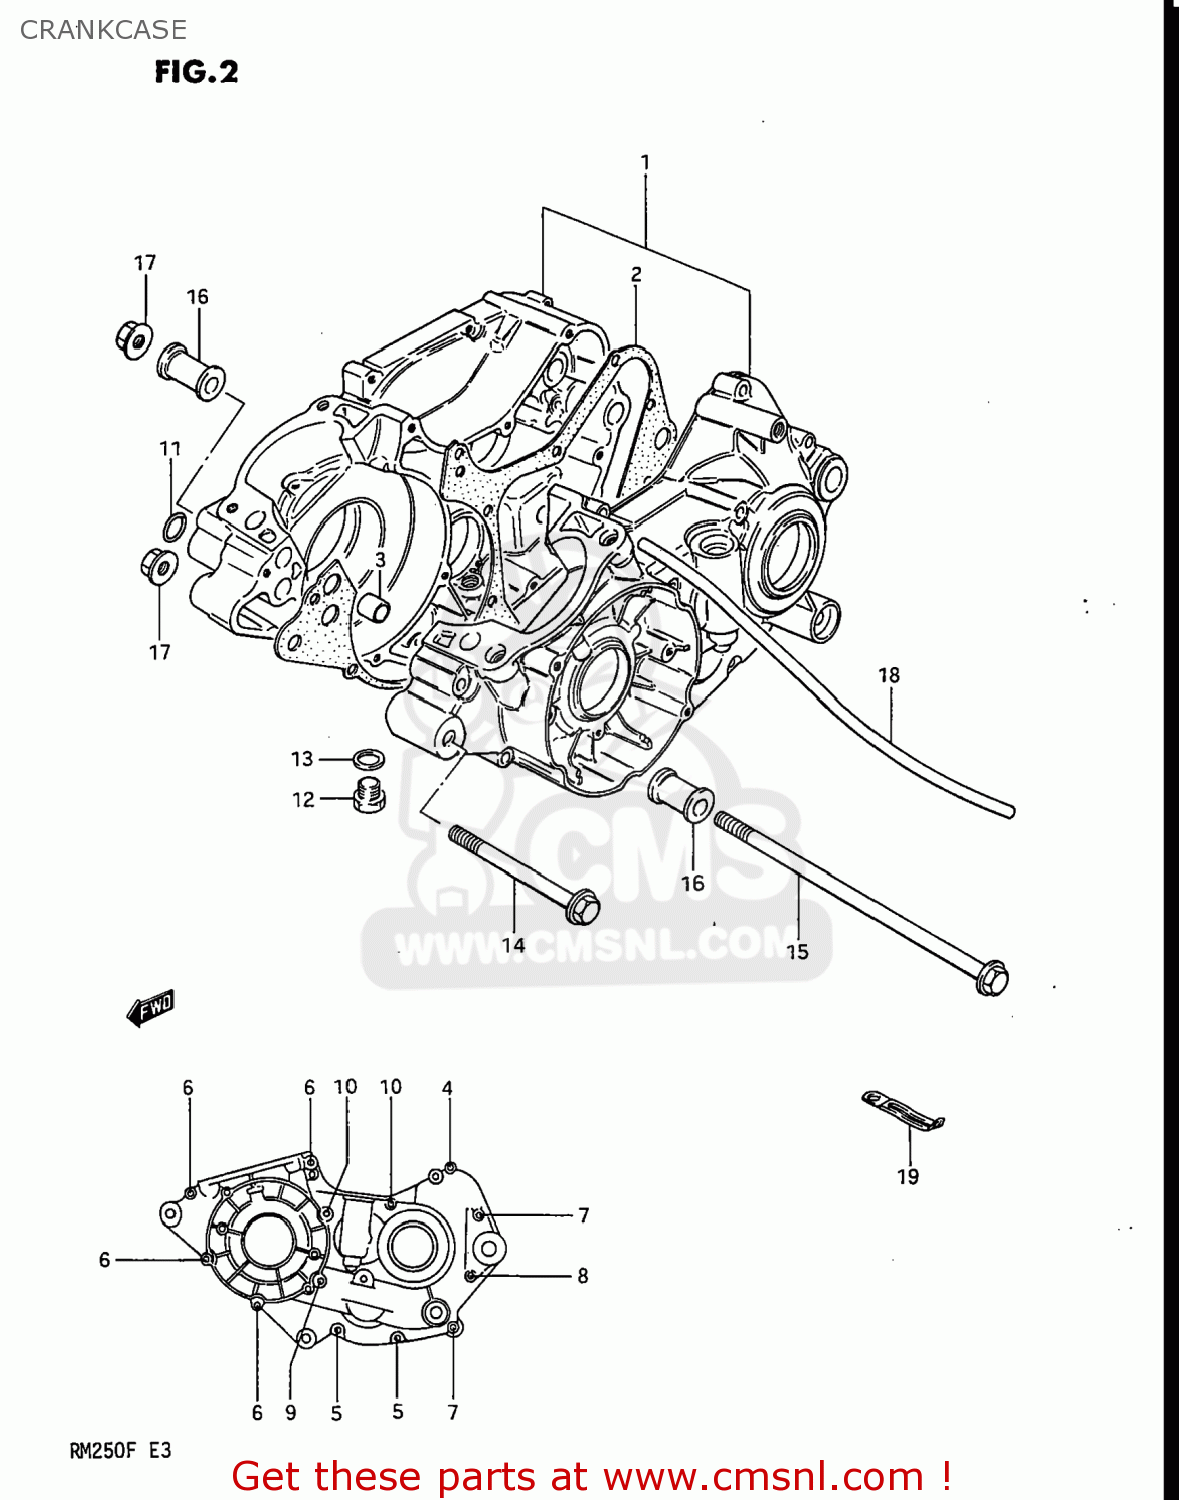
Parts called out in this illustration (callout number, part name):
1	CRANKCASE SET
2	GASKET,CRANKCASE (MCA)
3	PIN
4	SCREW
5	SCREW
6	SCREW
7	SCREW (6*50)
8	SCREW
9	SCREW (6*60)
10	SCREW
11	O RING(D:1.9,ID:13.8)
12	PLUG
13	GASKET(14X19.2X2) (NAS)
14	BOLT(8X100)
15	BOLT(8X225)
16	SPACER,ENGINE MOUNT
17	NUT
18	HOSE
19	CLAMP
